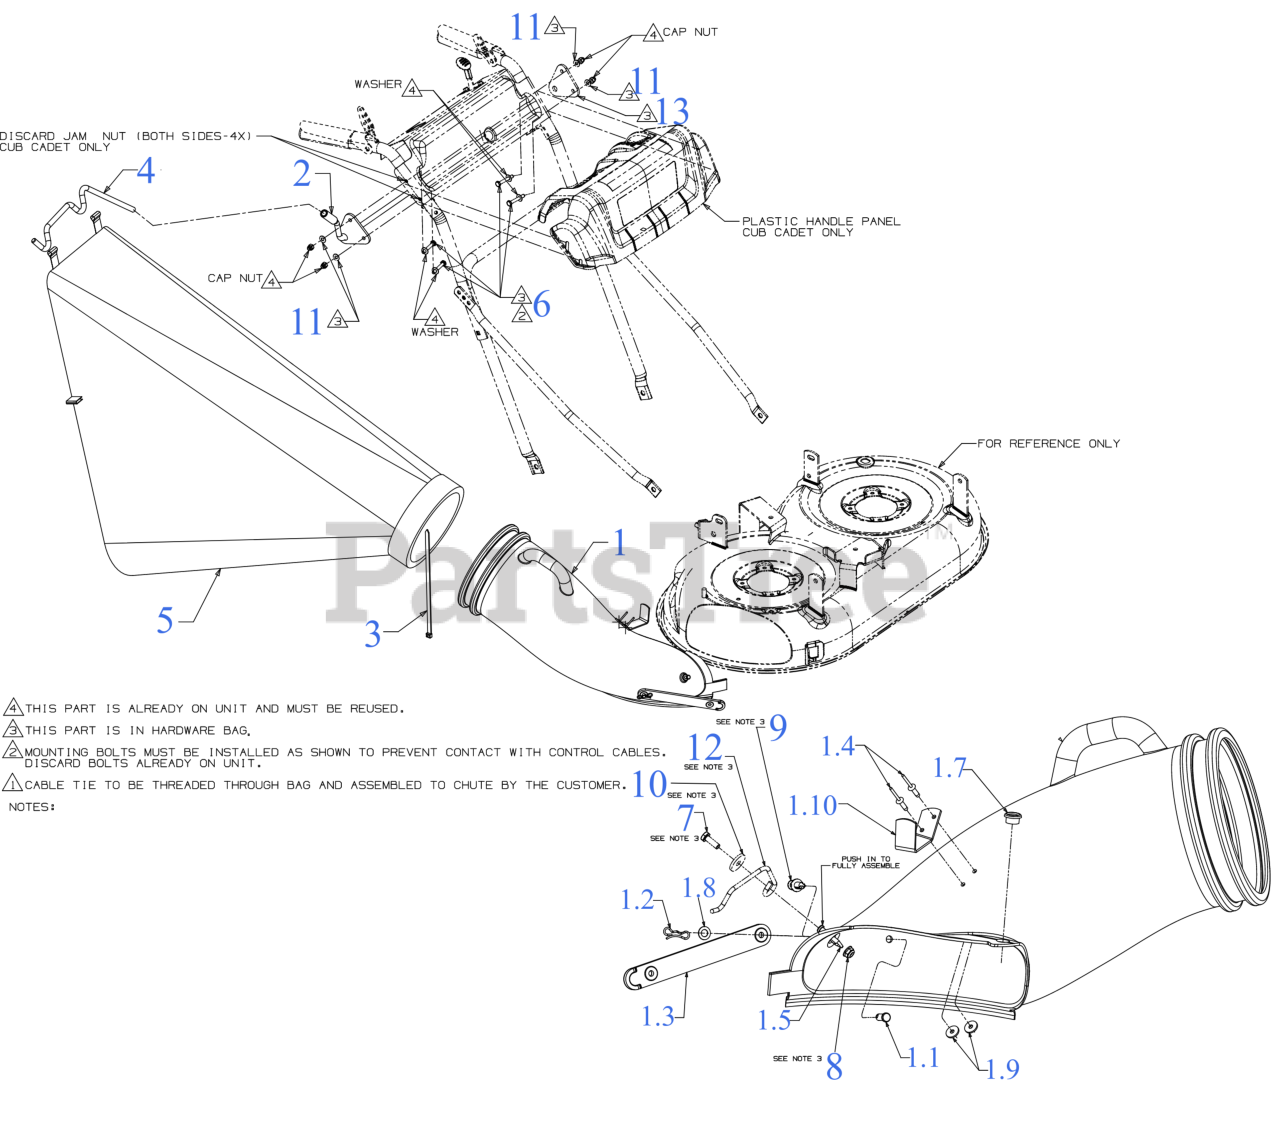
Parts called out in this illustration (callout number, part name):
1	SERVICE REPLACEMENT KITLAC
1.1	CLEVIS PIN 5/16 x 3/4
1.2	BOW TIE COTTER PIN 1/4-5/16
1.3	CHUTE STRAP
1.4	POP RIVET .187 DIA
1.5	PLASTIC RIVET .250
1.7	ROD CONTROL BUSHING
1.8	FLAT WASHER .344 ID x .62 OD x .033
1.9	FLAT WASHER .192X.625X.057
1.10	ELBOW HOLDER BRACKET
2	HOLDER ROD ASSEMBLY (POWDER BLACK)
3	CABLE TIE 36"
4	GRASSBAG HANGER ROD
5	GRASSBAG-2.6 BUSHE
6	HEX SCREW 1/4-20 x 1.75
7	SCREW 1/4-20X.75 GR5
8	FLANGE LOCK NUT
9	PLASTIC RIVET
10	FLAT WASHER
11	FLAT WASHER
12	ELBOW CHUTE LATCH (POWDER BLACK)
13	ROD HOLDER BRACKET
